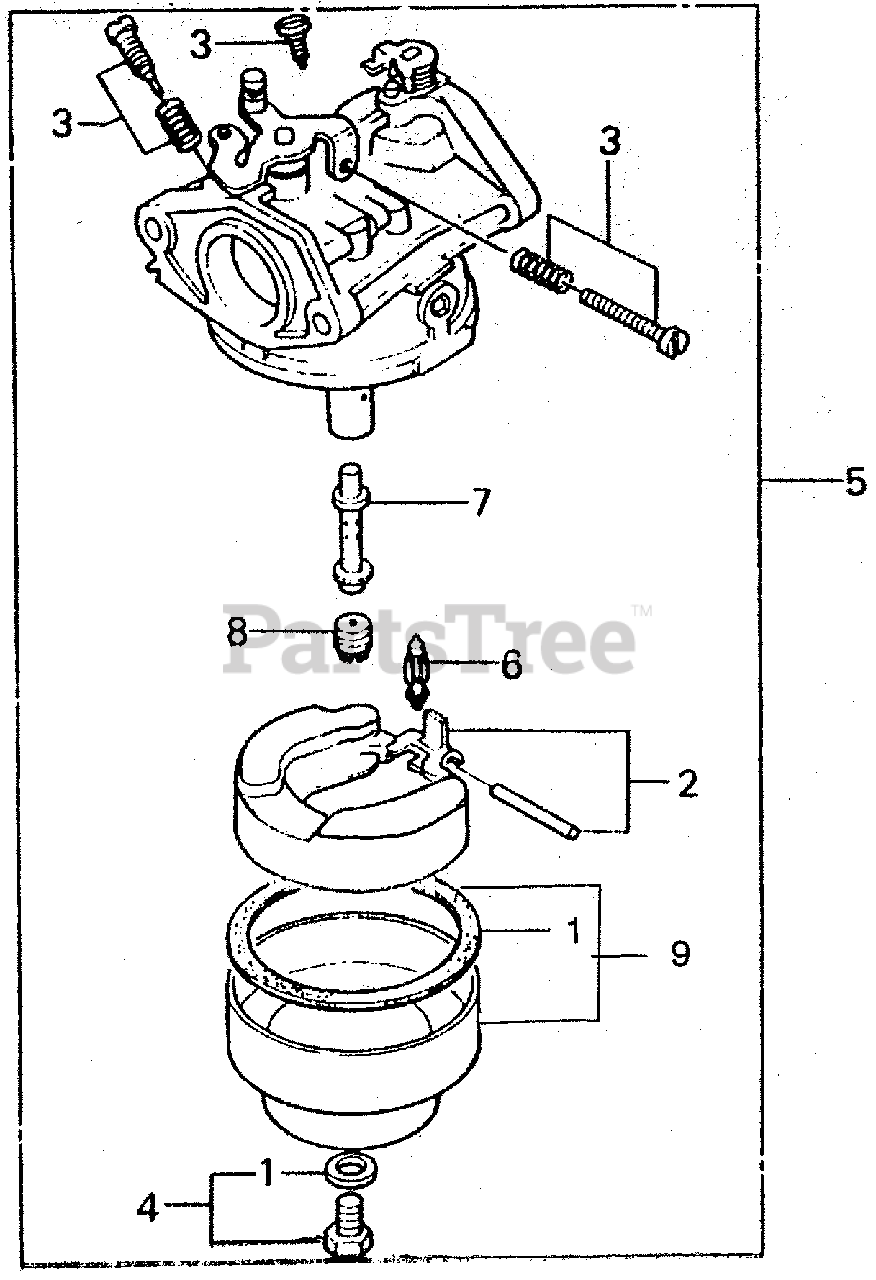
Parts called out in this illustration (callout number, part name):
1	GASKET SET
3	SCREW SET A
3	SCREW SET A (NOT AVAILABLE)
4	SCREW SET B
5	CARBURETOR ASSY. (BB27A E)
6	VALVE, FLOAT
7	NOZZLE, MAIN
8	JET, MAIN (#60)
8	JET, MAIN (#62)
8	JET, MAIN (#65)
9	CHAMBER SET, FLOAT
9	CHAMBER SET, FLOAT (NOT AVAILABLE)
